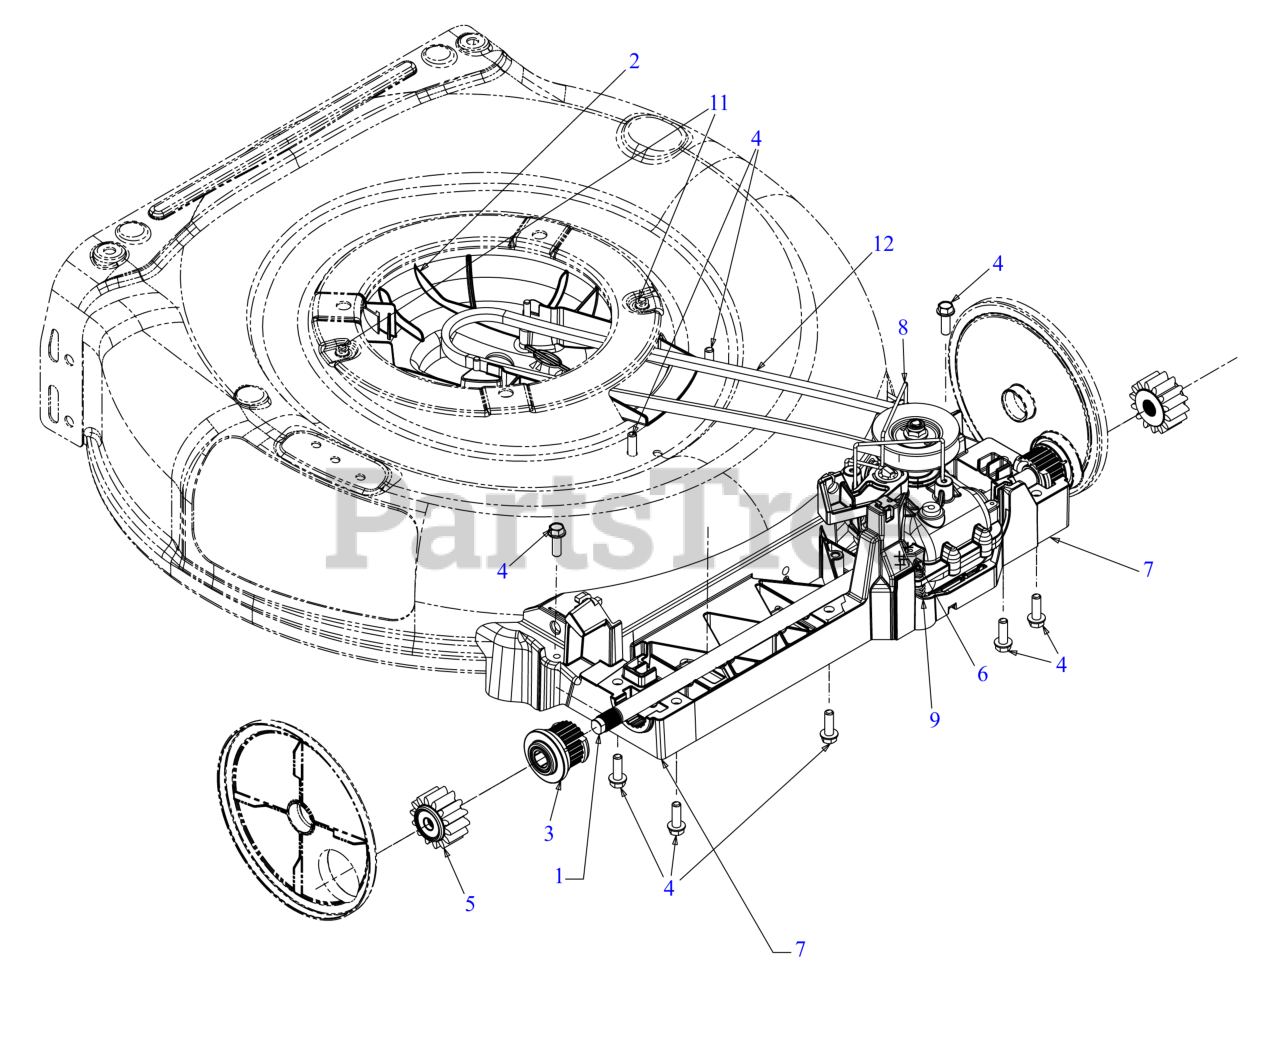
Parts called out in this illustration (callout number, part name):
1	TRANSMISSION ASSEMBLY
2	ENGINE BAFFLE ASSEMBLY
3	BEARING ASSEMBLY
4	SCREW 1/4-15 x .750
5	SPUR GEAR (14T) (RH)
6	SPRING COMPRESSION
7	LOWER TRAY
8	TRANSMISSION WIRE
9	COMPRESSION SPRING
11	SHOULDER SCREW 1/4-20 x .50
12	V-BELT 3L 34.18
